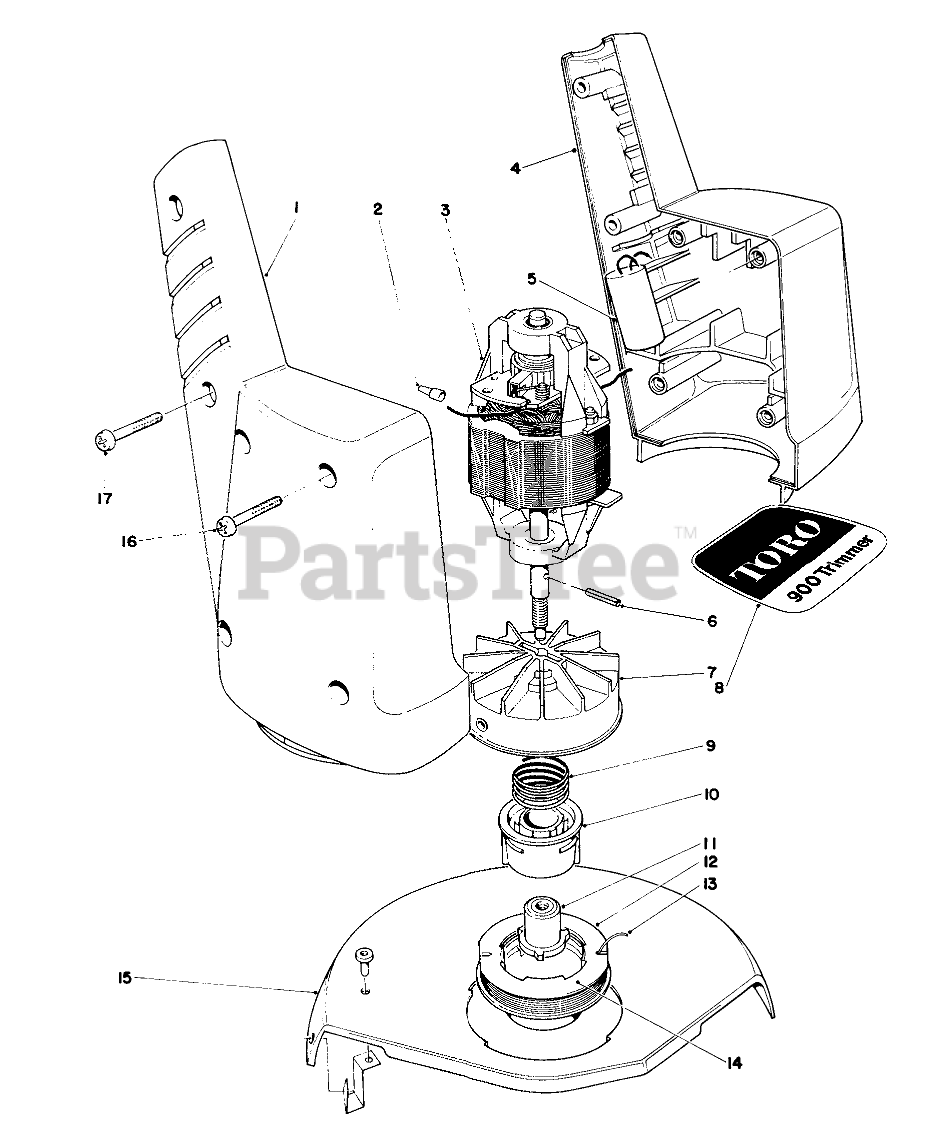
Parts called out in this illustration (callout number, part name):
1	Right Motor Housing
2	CONNECTOR WIRE JOINT
3	Motor
4	RH MOTOR HSG
5	Suppressor
6	COIL PIN
7	FAN HUB ASM
8	Toro 900 Decal
9	SPRING-COMPRESSION
10	CORE - SPOOL
11	Driver
12	SPOOL CAP
13	50- .040" Line In Coil
14	Prewound Spool
15	Shield with Cut-off Blade
16	SCREW-PPH
